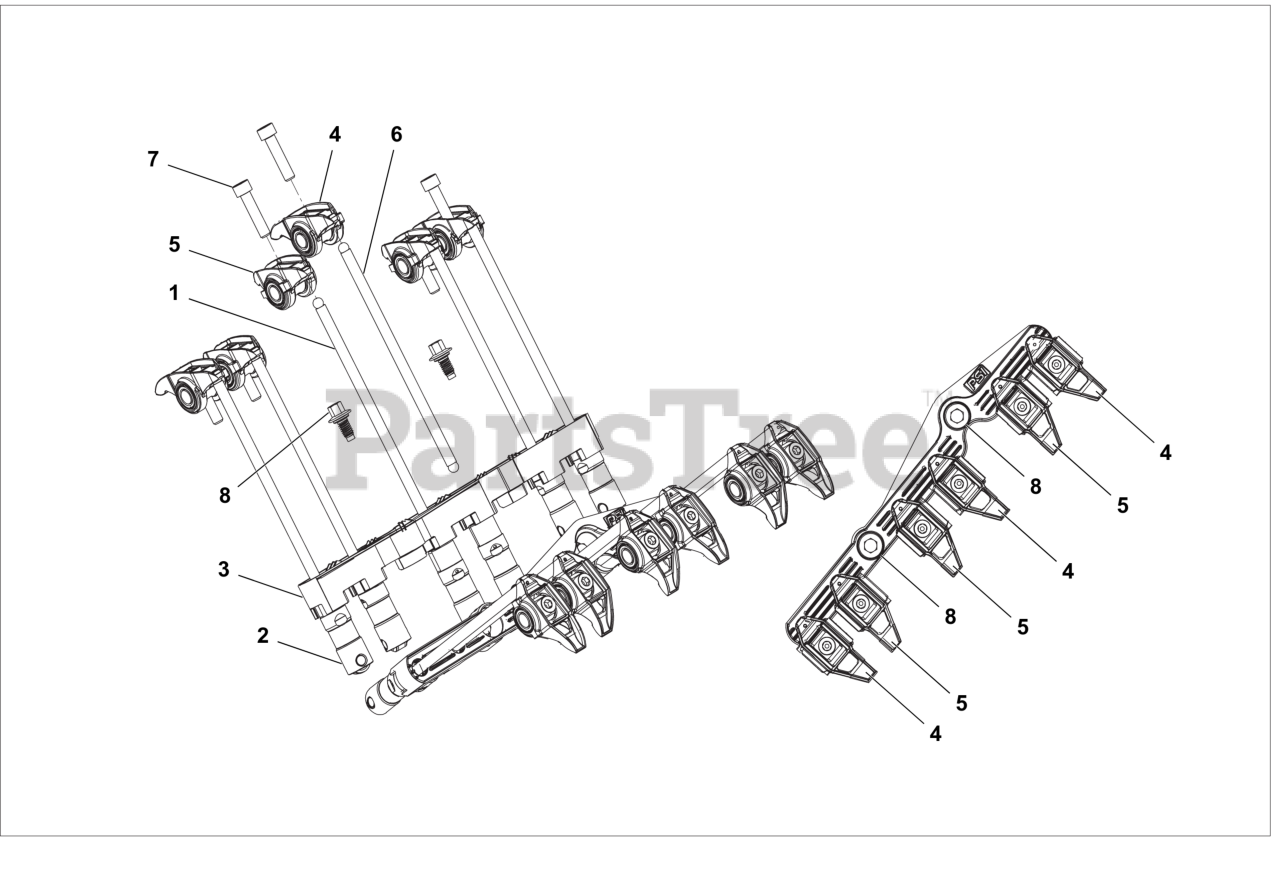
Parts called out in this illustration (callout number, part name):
1	*PUSH ROD (INTAKE)
2	*LIFTER
3	*LIFTER, BUCKET
4	*ROCKER ARM ASSEMBLY
5	*ROCKER ARM
6	*PUSH ROD (EXHAUST)
7	*BOLT, ROCKER ARM
8	*BOLT, LIFTER BUCKET
